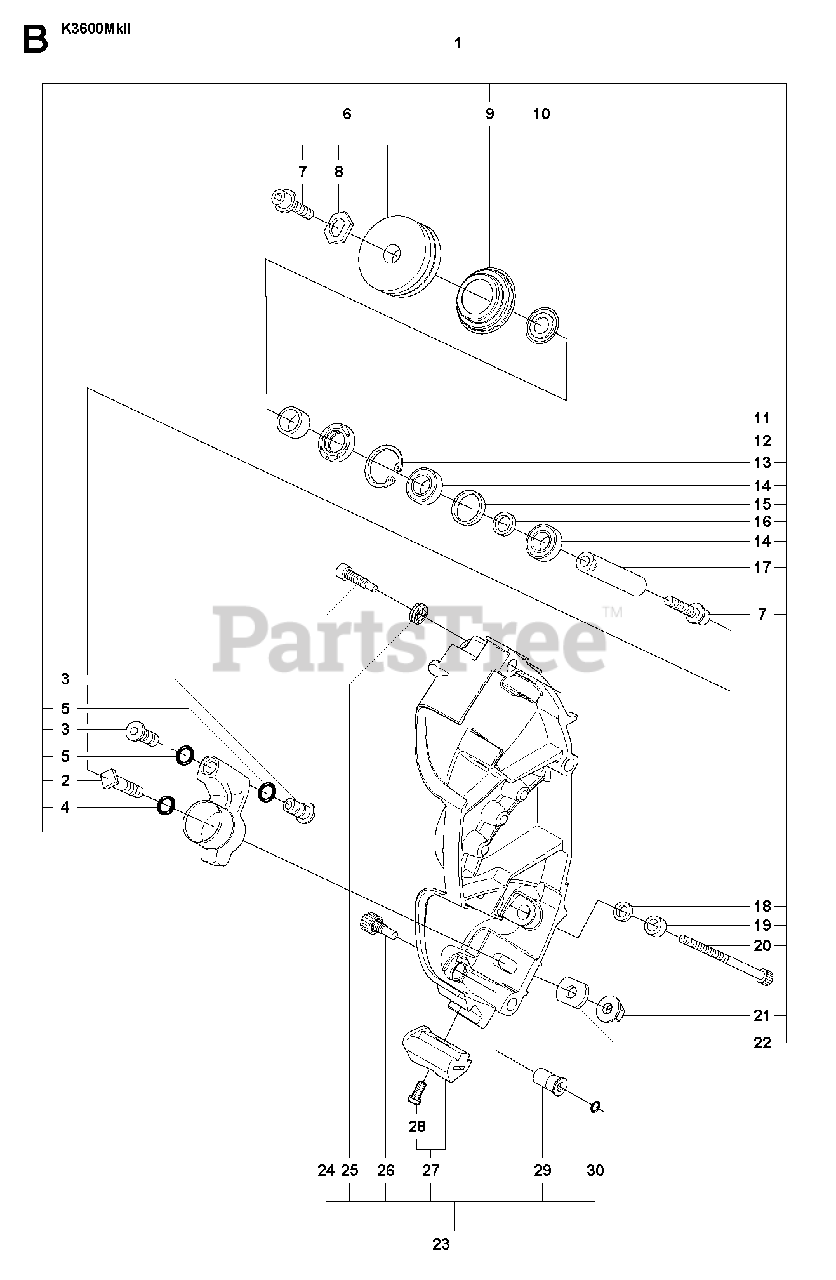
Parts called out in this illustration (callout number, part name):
1	LEVER ASSYIncl. 2 - 6, 9 - 23
6	SUPPORT ROLLERIncl. 7, 8
14	BALL BEARING
23	COVERIncl. 24, 25, 26 27, 29, 30
27	WEAR PROTECTIONIncl. 28
